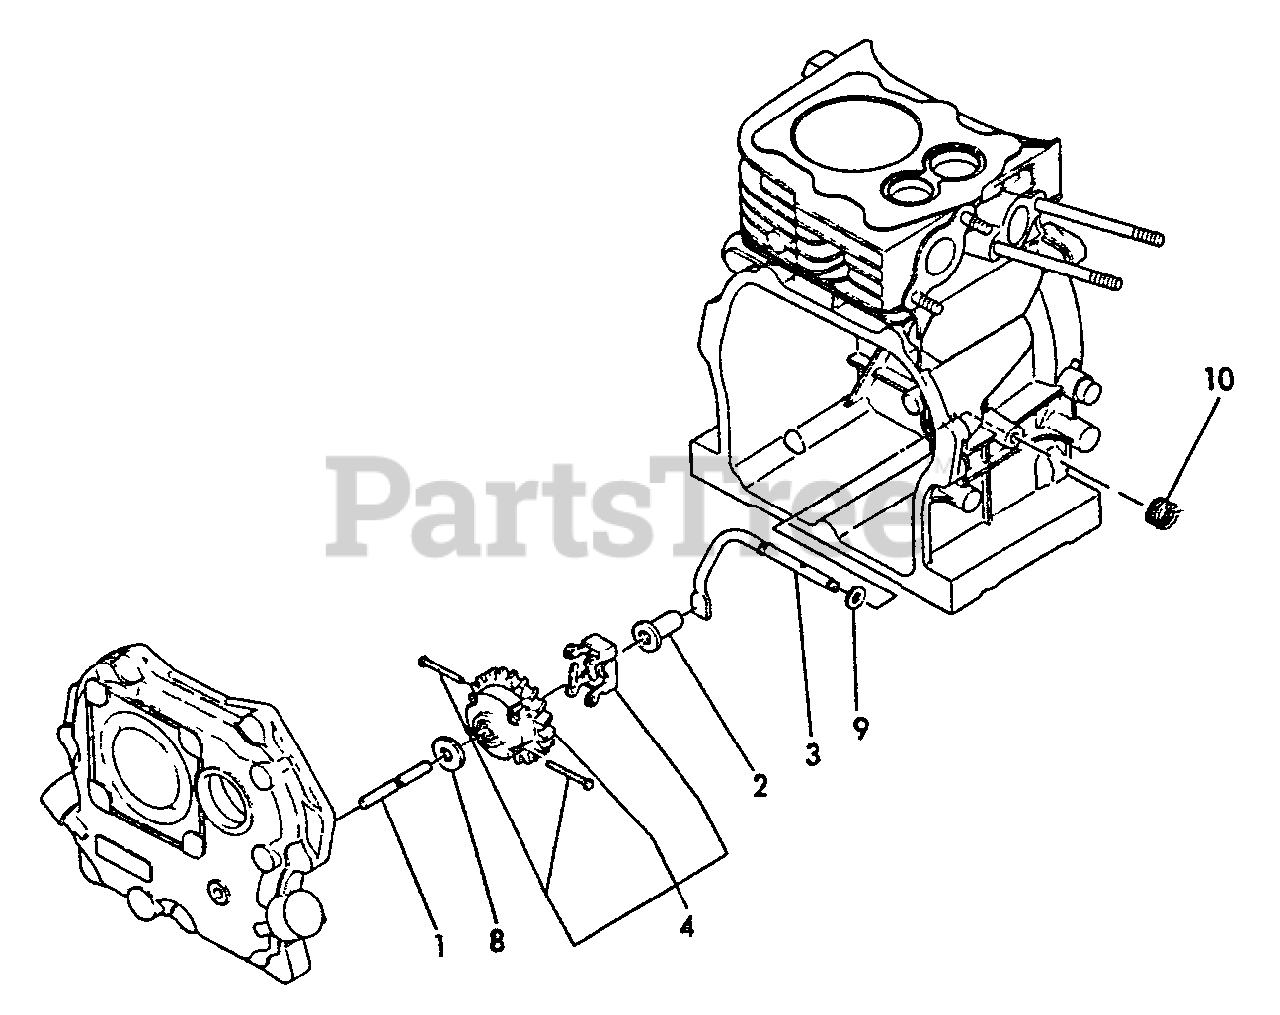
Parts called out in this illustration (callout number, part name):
1	SHAFT, GOVERNOR
2	SPINDLE, GOVERNOR
3	YOKE, GOVERNOR
4	GOVERNOR GEAR ASSY
8	WASHER - 6
9	WASHER - 6
10	SPRING, RETURN
